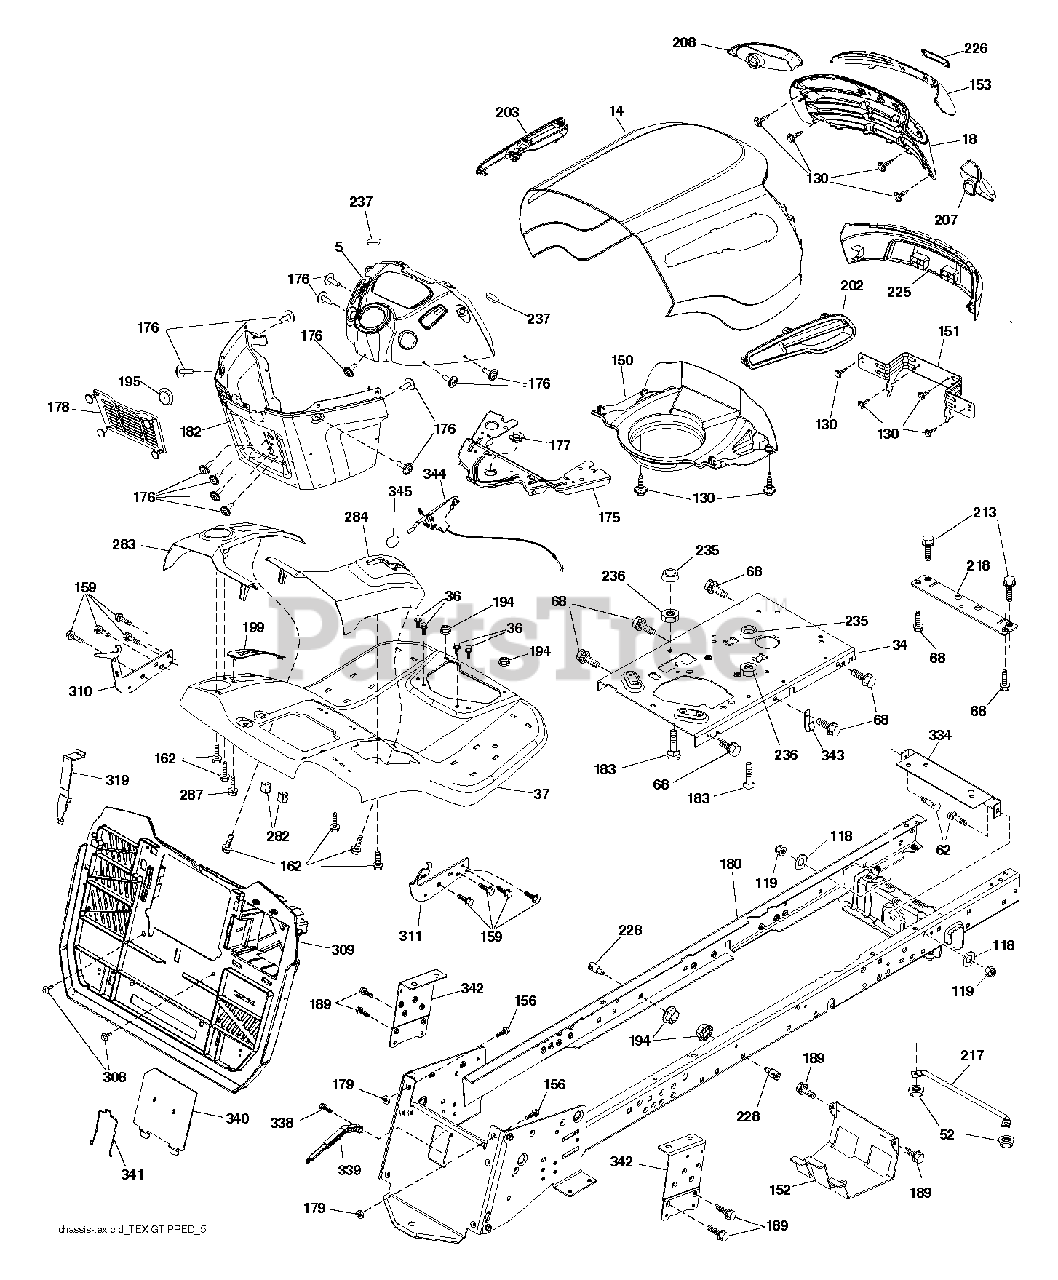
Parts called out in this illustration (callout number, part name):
36	SCREW 5/16"
52	LOCKNUT
119	LOCKNUT
130	SCREW.#10 X 0.750.BOS THREAD
150	PREDATOR.YT.GT.HOOD.A
152	SHIELD BROWNING
156	BOLT
159	SCREW, 3/8-16X3/4
162	SCREW.HI-LO.CONSOLE
175	PLATE.CROSSMEMBER.HUSQ
176	SCREW.#10-24X5/8.RN.QU
177	BUSHING,STEERING
178	CARGO.ASM.NET.TXGT.W/C
183	BOLT.5/16-18X1-1/4 FULL THD
189	SCREW
194	NUT LOCK HEX FLANGE 5/16-18
195	PLUG.HOLE.DASH.LOWER.12V.BLK
213	BOLT
217	ROD.PIVOT.HOOD
218	X-PIECE.HOOD.STOP.NON/
228	STUD.FASTNER.W/ANTI-ROTATE
235	SPACER FENDER
236	NUT.CENTERLOCK.5/16-
237	PLUG.MOUNT.CARGO.BLK
282	CLIP.RETAINER.CONSOLE.LT.HUSQ
308	BOLT, 5/16-18 X 1 3/4
